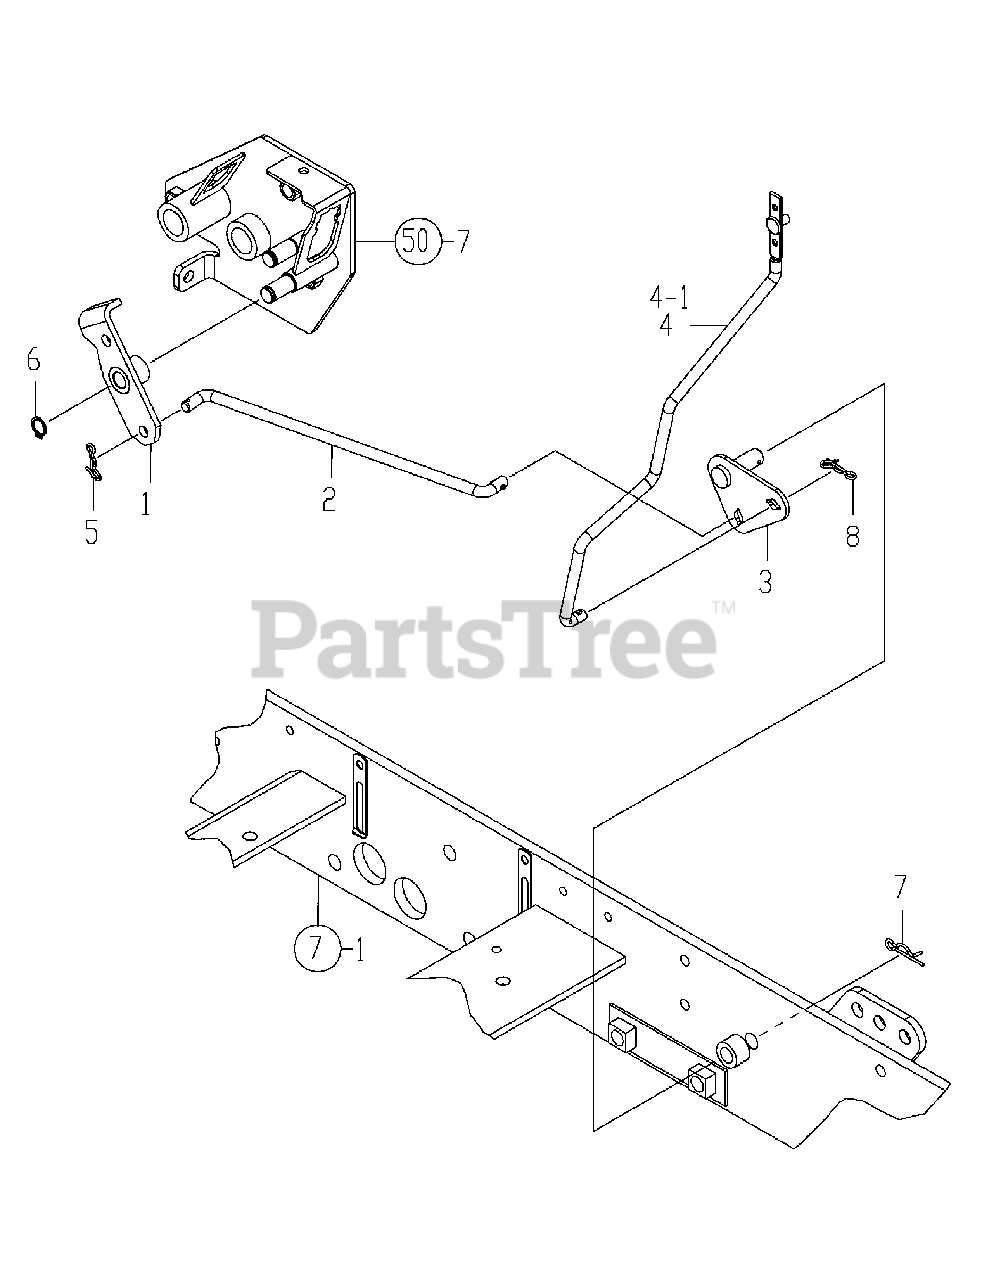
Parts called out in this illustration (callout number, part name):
1	ARM A,CRUISE CMP
3	LINK, CRUISE CMP
4	ROD B, CRUISE CMP
4-1	ROD B, CRUISE CMP
8	PIN, COME OFF SNAP
